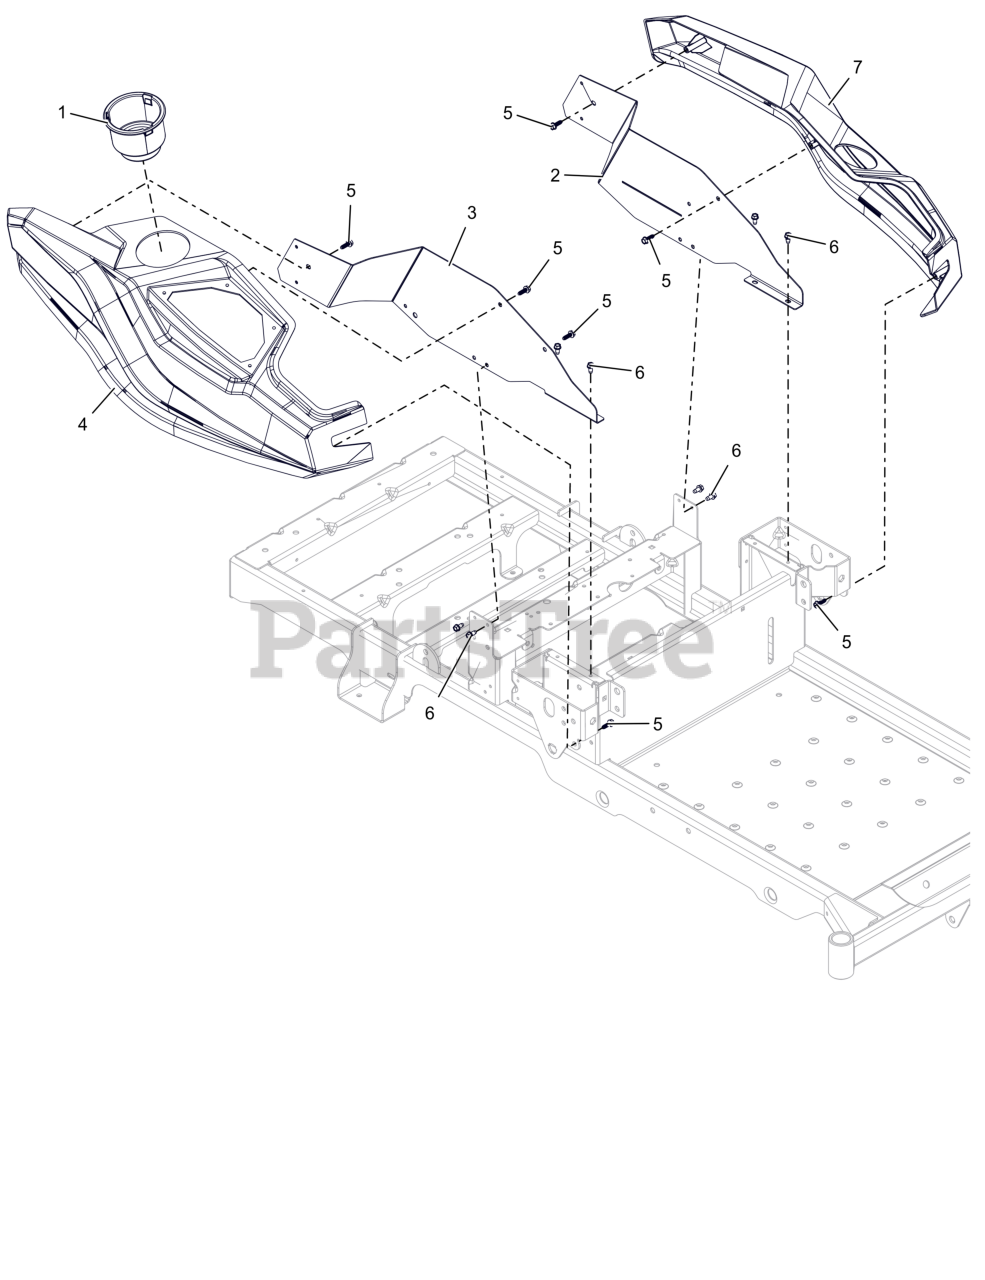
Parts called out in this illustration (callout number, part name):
1	CUPHOLDER, SNAP-IN 3.75OD
2	BRKT, FENDER MOUNTING LH (ORANGE)
3	BRKT, FENDER MOUNTING RH (ORANGE)
4	FENDER, RH - ZOOM
5	SCR, PLASTITE .25-10X.75 ZCC
6	SCR-TAP .25-20X.50 HWH ZCC
7	KIT-FENDER WITH DECAL
